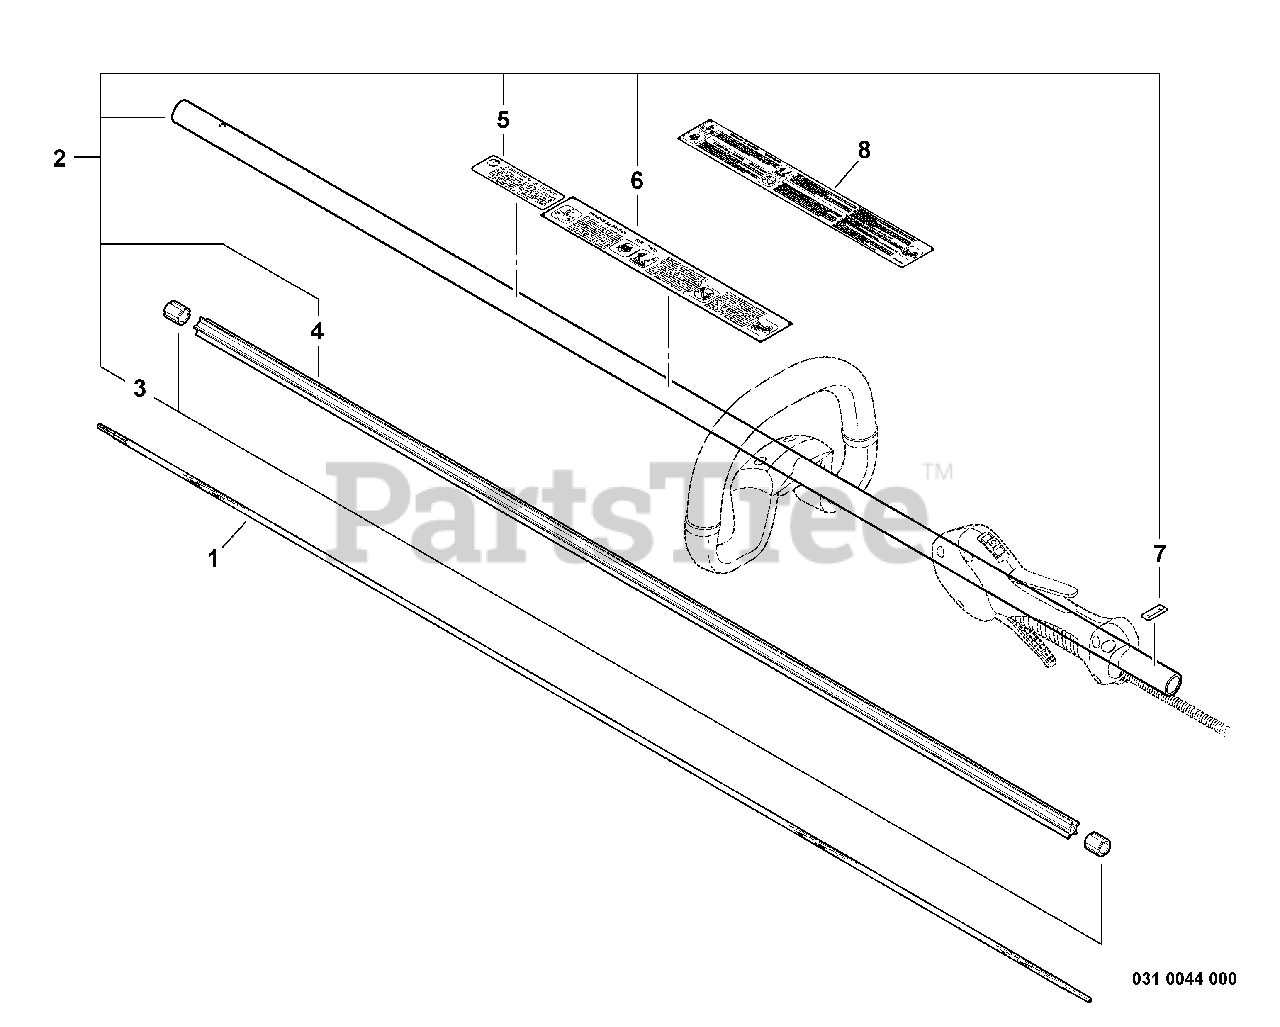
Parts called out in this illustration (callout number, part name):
1	DRIVESHAFT - FLEXIBLE L= 1522
2	MAIN PIPE ASSY 25×1500
4	LINER, FLEXIBLE 21.6×1420
5	LABEL, CAUTION
6	LABEL, CAUTION
7	LABEL - ALIGNMENT
8	LABEL, CAUTION
